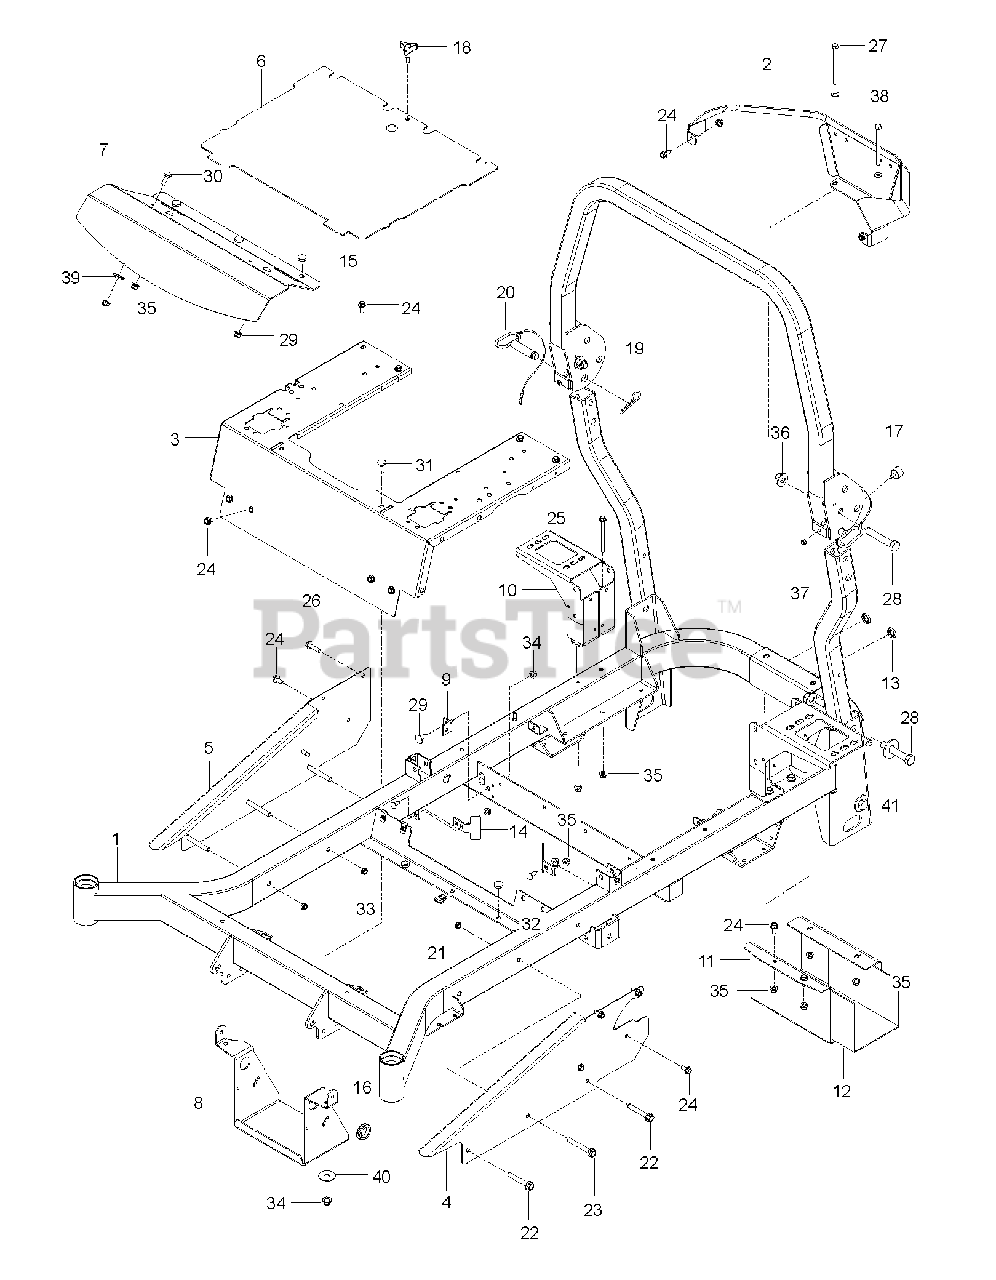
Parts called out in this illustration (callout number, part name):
1	KIT.FRAME.W/DECALS.X668
2	GUARD.PNT.REAR.MZ.GRAY
3	SUPPORT.PNT.SEAT.CONTROL.ORNG
4	SIDE.LT.ORANGE
5	SIDE.RT.ORANGE
6	PLATE, FLOOR W/DECALS
7	PLATE, FOOTREST
8	BRACKET.PNT.BATTERY.BLK
9	BRACKET.DAMPENER.BLACK
10	MOUNT, TANK, ZT BLK
11	SHIELD.MUFFLER.BLACK
12	HEAT SHIELD
13	CAP.PLUG.BP-1.BLACK
14	STOP, DECK, EZ+
15	GROMMET, BUMPER
16	RUBBER GROMMET
17	BUMPER, MALE STUD, 1/4-20
18	KNOB W/STUD
19	PIN HAIR .148 X 2-15/16 #210
21	U-CLIP 5/16-18 NUT RETAINER
22	HHFS 3/8-16 X 2.5 GR 5 ZD
23	HHFS 3/8-16 X 2-3/4 GR5 ZD
24	HHFS 5/16-18 X 3/4
25	BOLT.HEX.FLNG.5/16-18X3.75
26	HHFS 5/16-18 X 1.25 TPBLT GD 5
27	HCS 5/16C X 4
28	5/8-11 X 3-1/2 HHB GRADE 5
29	BOLT 5/16-18 X3/4 ZN/YEL GR 5
30	RHSNB 5/16C X 1
31	RHSNB 3/8C X 1
32	BOLT 5/16C X 3/4" CARRIAGE
33	NUT HEX 3/8-16 NYLON, THIN
34	NUT 3/8-16 HEX FLG NYLOC ZD
35	5/16-18 NYLOC FLANGE NUT
36	NUT 5/8-11 FLG NYLOC ZD
37	RP_NUT 1/4-20 NYLOC
38	WASHER
39	WASHER 1/2" FLAT
40	WASHER.13/32X1-1/2X16GA
41	WASHER, 5/8 FLAT
